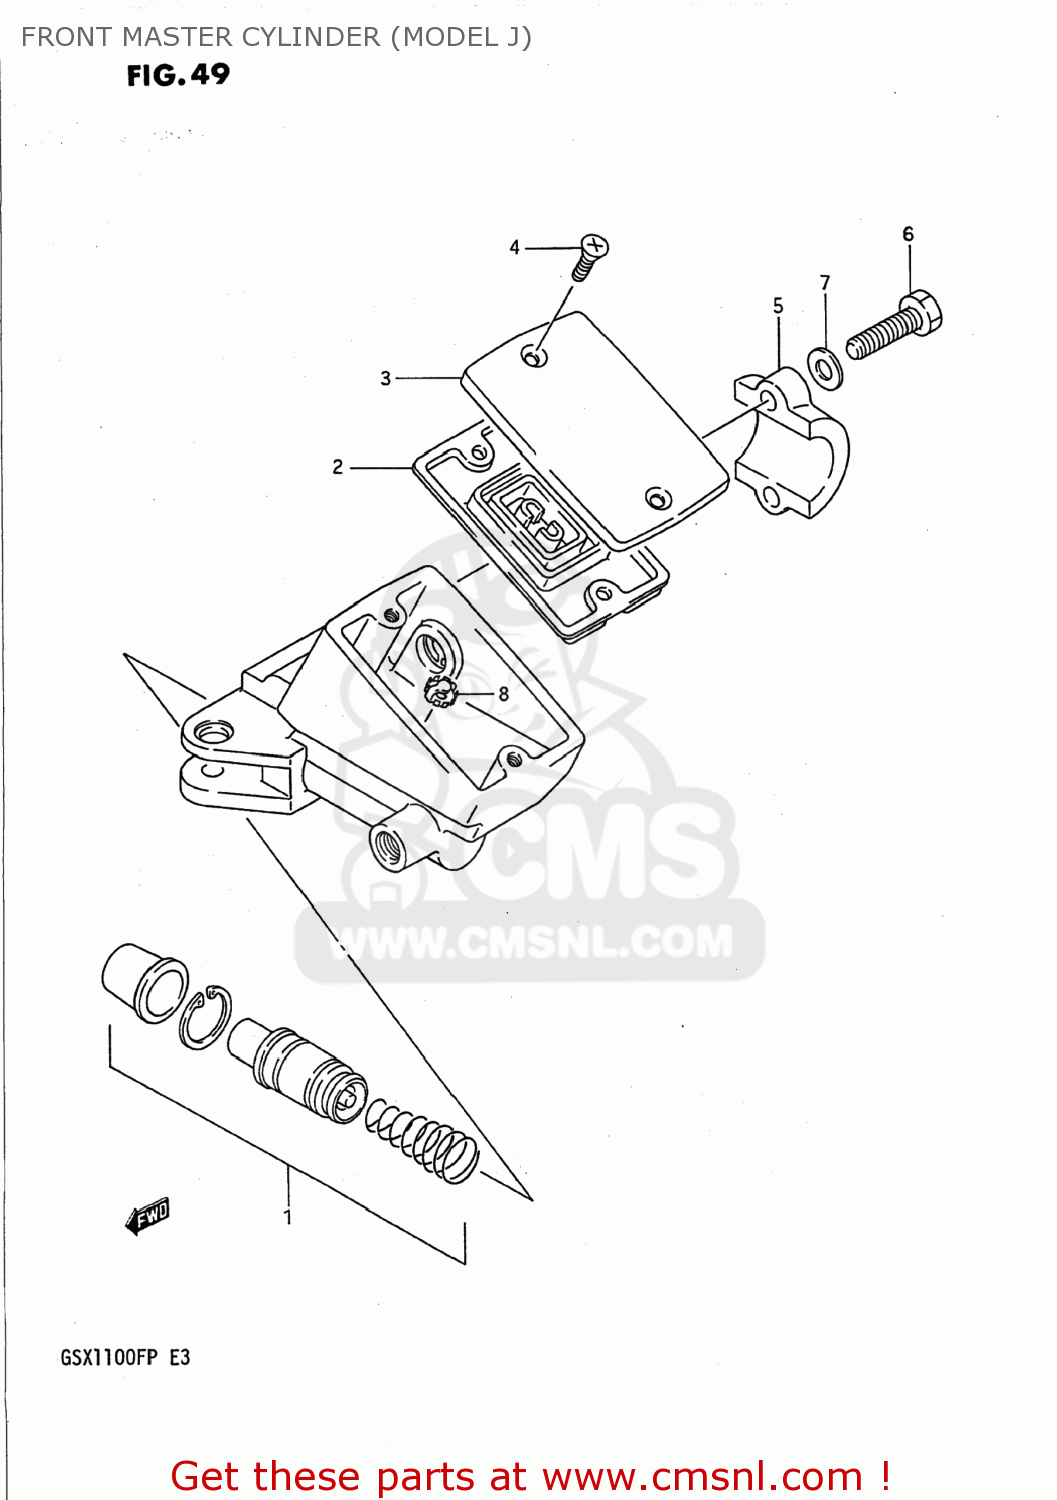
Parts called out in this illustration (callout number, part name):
1	PISTON & CUP SET
2	3-1
3	CAP
4	SCREW
5	HOLDER
6	BOLT
7	WASHER
8	PROTECTOR
